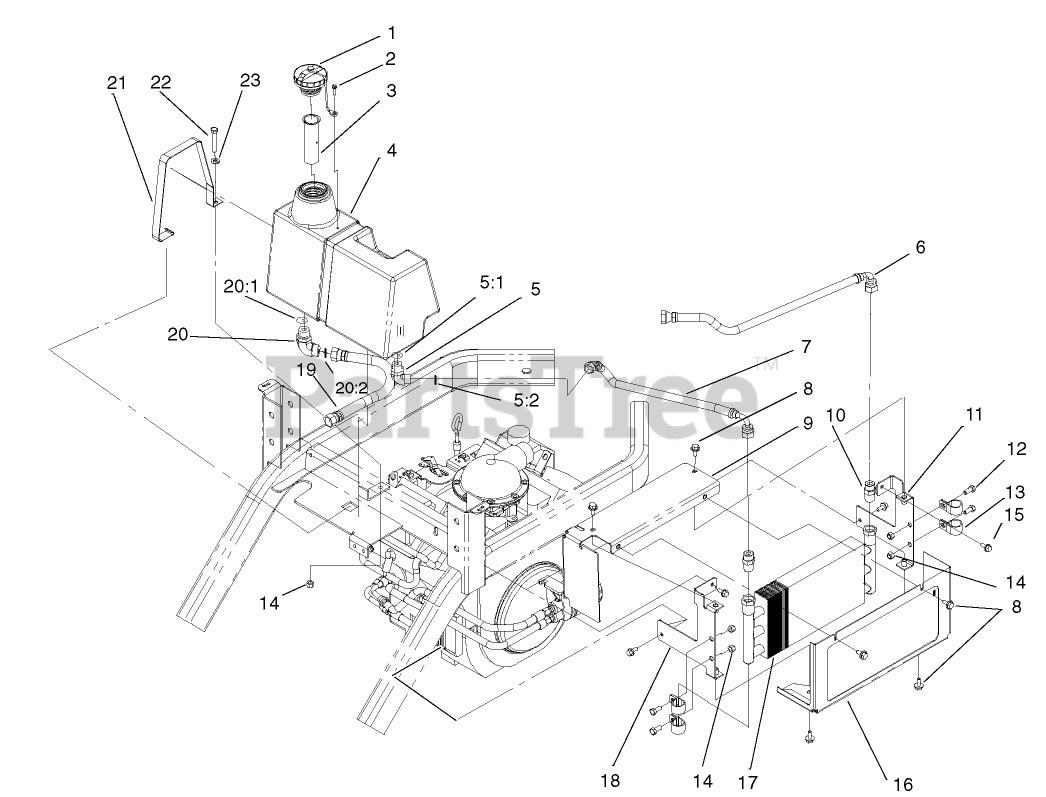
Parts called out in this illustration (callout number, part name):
1	CAP-OIL
2	SCREW-HWH
3	FILTER-SCREEN
4	TANK-HYD
5	FITTING-ELBOW-90 DEG
5:1	O-RING
5:2	O-RING
6	HYDRAULIC HOSE ASM
7	HYDRAULIC HOSE ASM
8	SCREW-HHF
9	COOLER SHROUD ASM
10	FITTING-ADAPTER
11	REAR COOLER BRACKET ASM
12	SCREW-HH
13	CLAMP-R
14	NUT-LOCK, NI
15	SCREW-HWH
16	COOLER SHROUD ASM
17	COOLER ASM
18	FRONT COOLER BRACKET ASM
19	HYDRAULIC HOSE ASM
20	FITTING-ELBOW 90
20:1	O-RING
20:2	O-RING
21	STRAP-TANK, HYD
22	SCREW-HH
23	WASHER-PLAIN
